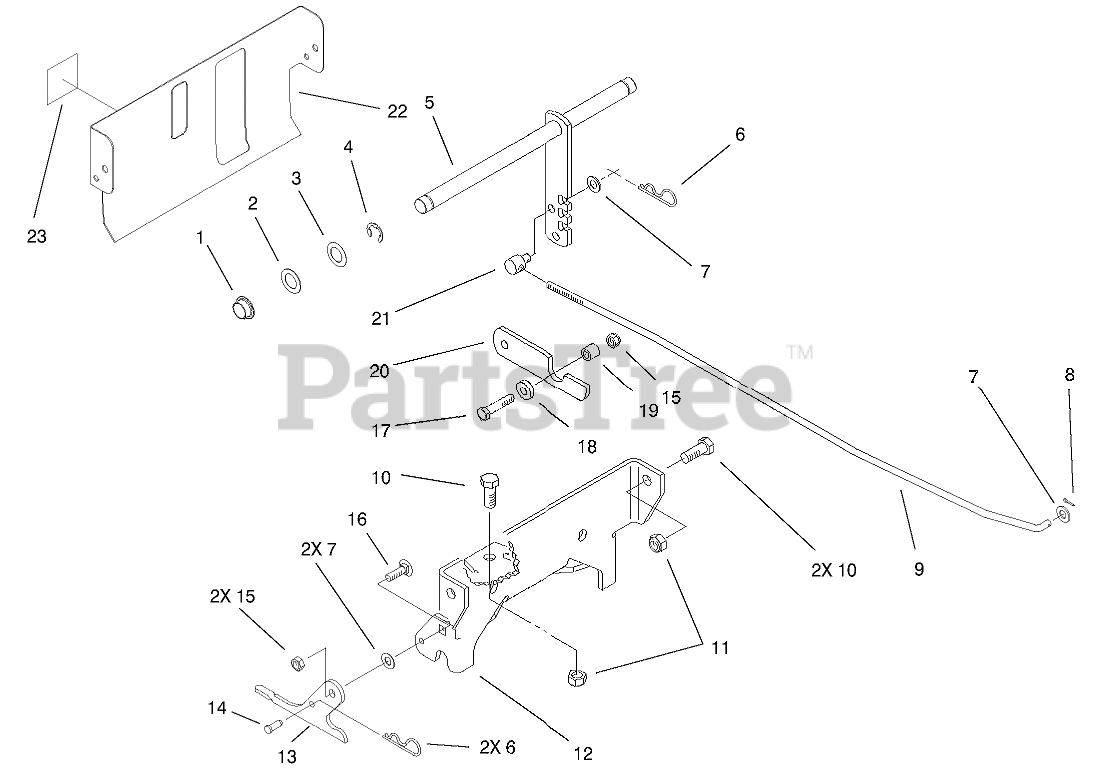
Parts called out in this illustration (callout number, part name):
1	BUSHING-BRONZE
2	WASHER
3	WASHER-SHIM
4	E-RING
5	LEVER ASM
6	PIN-HAIR
7	WASHER-FLAT
8	PIN-COTTER
9	ROD-LIFT
10	SCREW-HH
11	NUT-LOCK, NI
12	BRACKET-MOUNTING
13	PLATE-LATCHING
14	PIN-CLEVIS
15	NUT-LOCK, NI
16	BOLT-CARR
17	SCREW-HH
18	Washer
19	SPACER
20	CATCH-SPRING
21	TRUNNION-CLUTCH ROD
22	COVER-REAR
23	DECAL-LEVEL, FUEL
